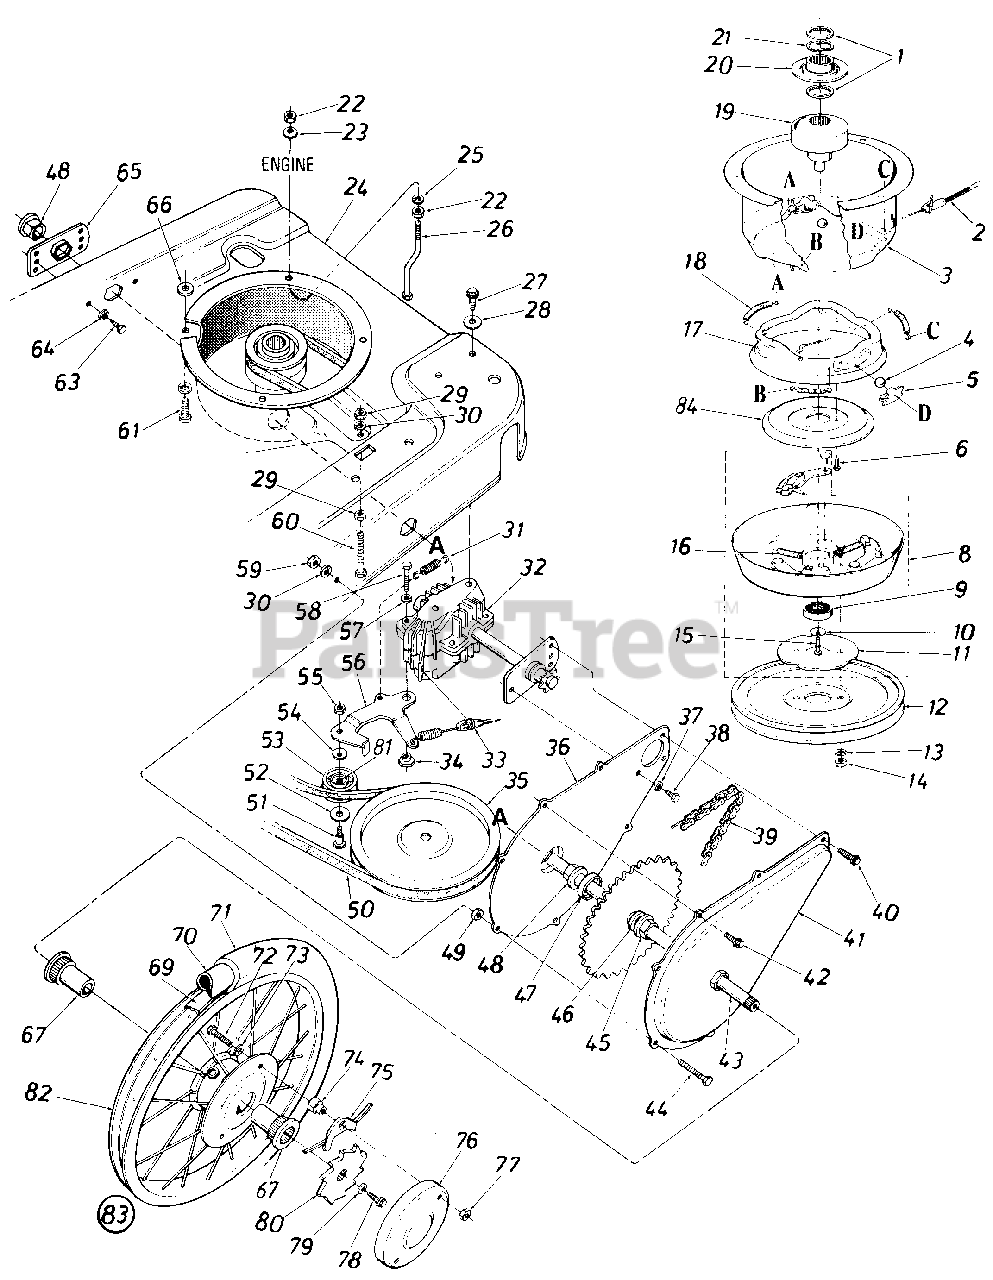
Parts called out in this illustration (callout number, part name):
1	Washer 1.0" I.D. x 1.2" O.D.
2	BBC Clutch Cable 46" Lg.
3	Clutch Housing
4	Steel Ball .500" Dia.
5	Ball Block
6	Hex Wash. TT-Tap Cl. Scr. 1/4-20 x .75" Lg.
8	Clutch Blade Housing Ass'y.
9	Ball Brg. .669" I.D. x 1.574" O.D.
10	Bell-Wash 44" I.D. x .87" O.D.
11	Blade Disc.
12	5/8 "V"-Pulley 1.58" I.D. x 8.0" O.D.
13	L-Wash. 3/8" I.D.
14	Hex Nut 3/8-24 Thd.
15	Hex Bolt 7/16-20 x 2.0" Lg.- Gr. 5
16	Comp. Spring .33" O.D. x 2.05" Lg.
17	Brake Cup Cone
18	Extension Spring .35" O.D. x 1.80" Lg.
19	Fixed Pulley MBC Adapter
20	Movable Pulley Half
21	Wave Wash. .164 High x 1.005" I.D.
22	Hex Nut 5/16-18 Thd.
23	Bell-Wash. .336" I.D. x .860" O.D.
24	Hi-Wheel Fram
25	L-Wash. 5/16" I.D.
26	Belt Guard 5/16" Bolt
27	Hex Wash. Hd. B-Tap Scr. 5/16-18 x .50" Lg.
28	Bell-Wash. .378" I.D. x 1.110" O.D.
29	Hex Nut 1/4-20 Thd.
30	L-Wash. 1/4" I.D.
31	Extension Spring .33" I.D. x 1.12" Lg.
32	Transmission Comp.
33	Self-Propelled Cable x 50" Lg.-Black
34	Shld. Spacer.375" Dia. x .1 70
35	Fl-Pulley 5.06" O.D.
36	45 Tooth Chain Cover
37	L-Wash. 1/4" I.D.
38	Hex B-Tap Scr. 1/4 x .38" Lg.
39	#48 Chain .500" Pitch x 52 Links
40	Hex Wash. TT-Tap Scr. 1/4-20 x .50" Lg.
41	45 Tooth Chain Case
42	Hex B-Tap Scr. 1/4 x .38" Lg.
43	Rear Axle Ass'y. 26.82" Lg.
44	Hex Bolt 1/4-28 x .88" Lg.
45	Hex Flange Brg. .631" I.D. x .320
46	Fl-Wash. .635" I.D. x 1.0" O.D.
47	Spacer .630" I.D. x 1.250" O.D.
48	Hex Flange Brg. .631" I.D. x .720
49	Hex Jam Nut 1/4-28 Thd.
50	"V"-Belt
51	Shld. Bolt .375" Dia. x .400 Lg.
52	Fl-Wash. .390" I.D. x 1.00" O.D.
53	Fl-Idler Plastic 1.50" Dia. x .48
54	Bell-Wash. .265" I.D. x .75" O.D.
55	Hex Patch L-Nut 1/4-28 Thd.
56	Idler Brk't. Ass'y.
57	L-Wash. #10
58	Hex Bolt 1/4-20 x 1.25" Lg.
59	Hex Nut 1/4-28 Thd.
60	Hex Bolt 1/4-20 x 2.00" Lg.
61	Hex Wash. Hd. TT-Tap Scr. 3/8-16 x 1.0" Lg.
63	Hex B-Tap Scr. 1/4 x .38" Lg.
64	L-Wash. 1/4" I.D.
65	Hex Bearing Cup
66	Fl-Wash. .406" I.D. x .734" O.D.
67	Flange Bearing .630" I.D. x 2.83" Lg.
69	Rimstrip 16 x 7/8
70	Inner Tube 16 x 2.12
71	Chevron Tire 16 x 2.125
72	Hex Bolt Special 5/16-18 x 1.0" Lg.
73	Intern. L-Wash. 5/16" I.D.
74	Special Hex Nut 5/16-18 Thd.
75	Pawl and Spring Ass'y.
76	Wheel Cover 4.75" I.D.
77	Hex Nut 5/16-18 Thd.
78	Hex Wash. Hd. Self-Tap Screw 1/4" x 3/4" Lg.
79	Bell-Wash. .265" I.D. x .75" O.D.
80	Wheel Ratchet 2.92" O.D.
81	Needle Brg. .375" x .31"
82	Rim Ass'y. Only 16.0" x 2.1
83	Wheel Ass'y. Comp. 16 x 2.12
84	Clutching Cone
